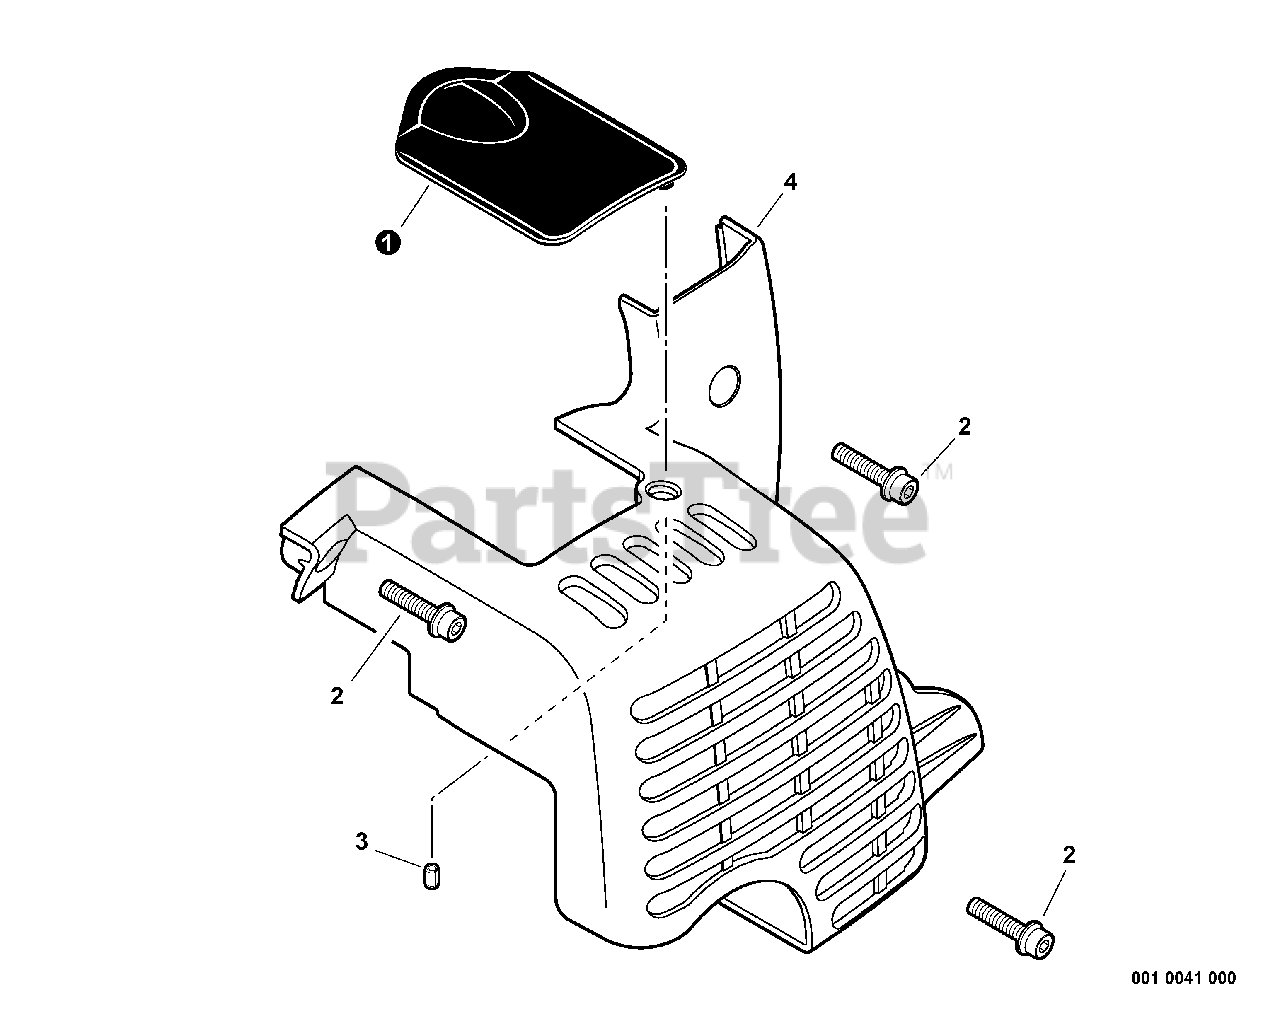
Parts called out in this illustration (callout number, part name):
1	COVER, SPARK PLUG
2	SCREW - 5X20
3	PIN - SPRING -- 4X8
4	COVER, ENGINE
